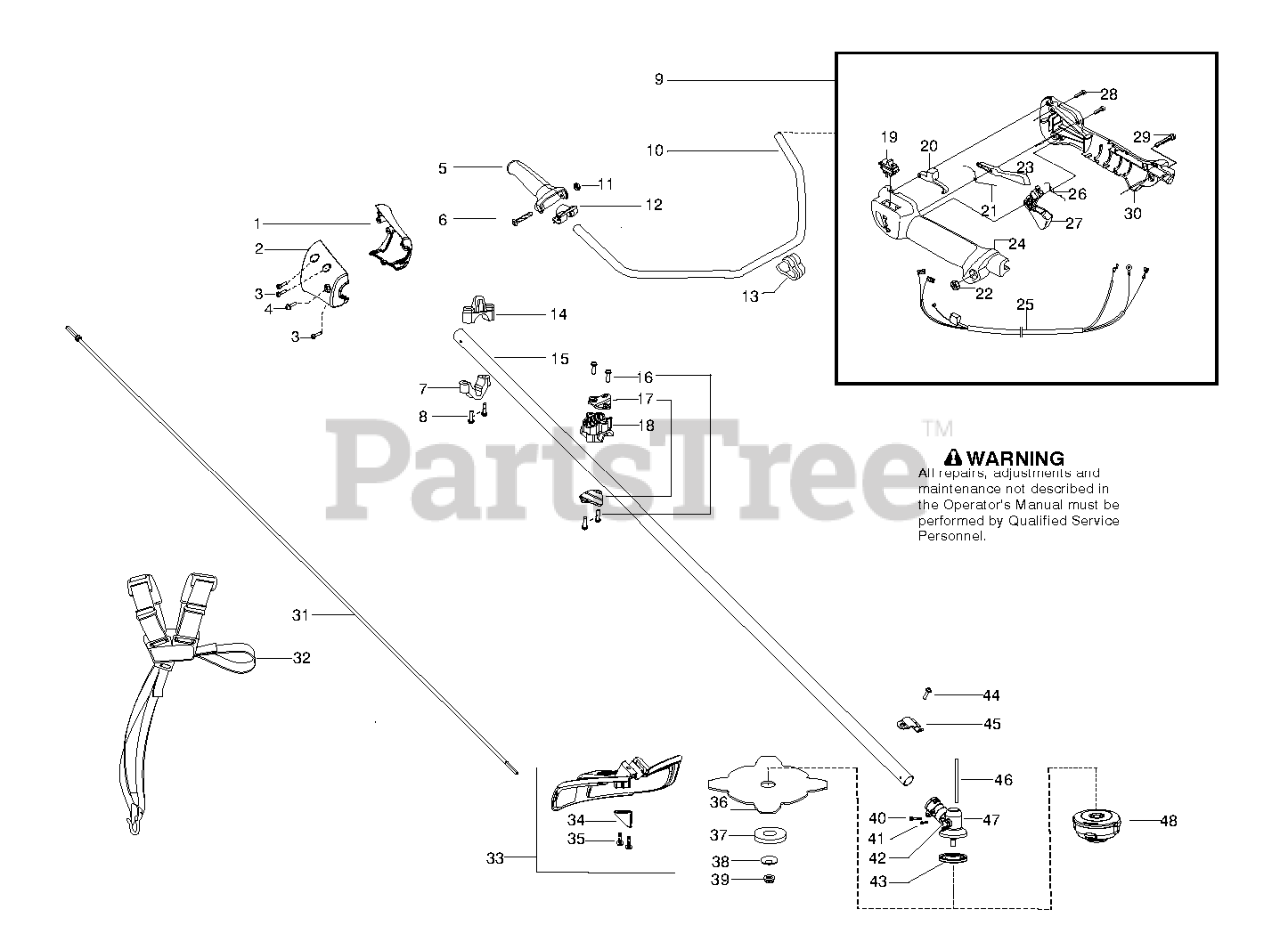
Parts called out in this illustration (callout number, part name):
1	NOSE CONE B/H LH HVA 25.4MM
2	CONE
3	SCREW M4 X 1.75 PT 16MM
4	SCREW-10-14 X 1/2 PLASTITE
7	CLAMP HARNESS LOWER
9	ASSY THROTTLE HOUSING
14	CLAMP HARNESS UPPER
15	KIT - DRIVESHAFT
15	Kit-Driveshaft
17	CLAMP BRACKET
19	STOP BUTTON
20	STARTER THROTTLE LOCK
23	THROTTLE LOCKOUT
25	ASSY CABLE WIRE HARNESS
27	THROTTLE CONTROL
29	SCREW
31	FLEXSHAFT 57"
32	HARNESS DUO
33	KIT COBI SHIELD
34	Limiter - Line
36	Blade - Grass
37	SUPPORTING CUP
38	SUPPORT FLANGE
39	GEARHEAD NUT - BRUSHCUTTER
40	SCREW - CARB. ADAPTOR
42	PLUG GREASE 9MM
43	DRIVE DISC
44	SCREW 1/4-20 X 7/8 (TAP
45	BRACKET SHIELD STRAIGHT SHAFT
46	LOCKING PIN
47	ASSY GEARBOX
48	T25 TRIM HEAD 10MM LH
